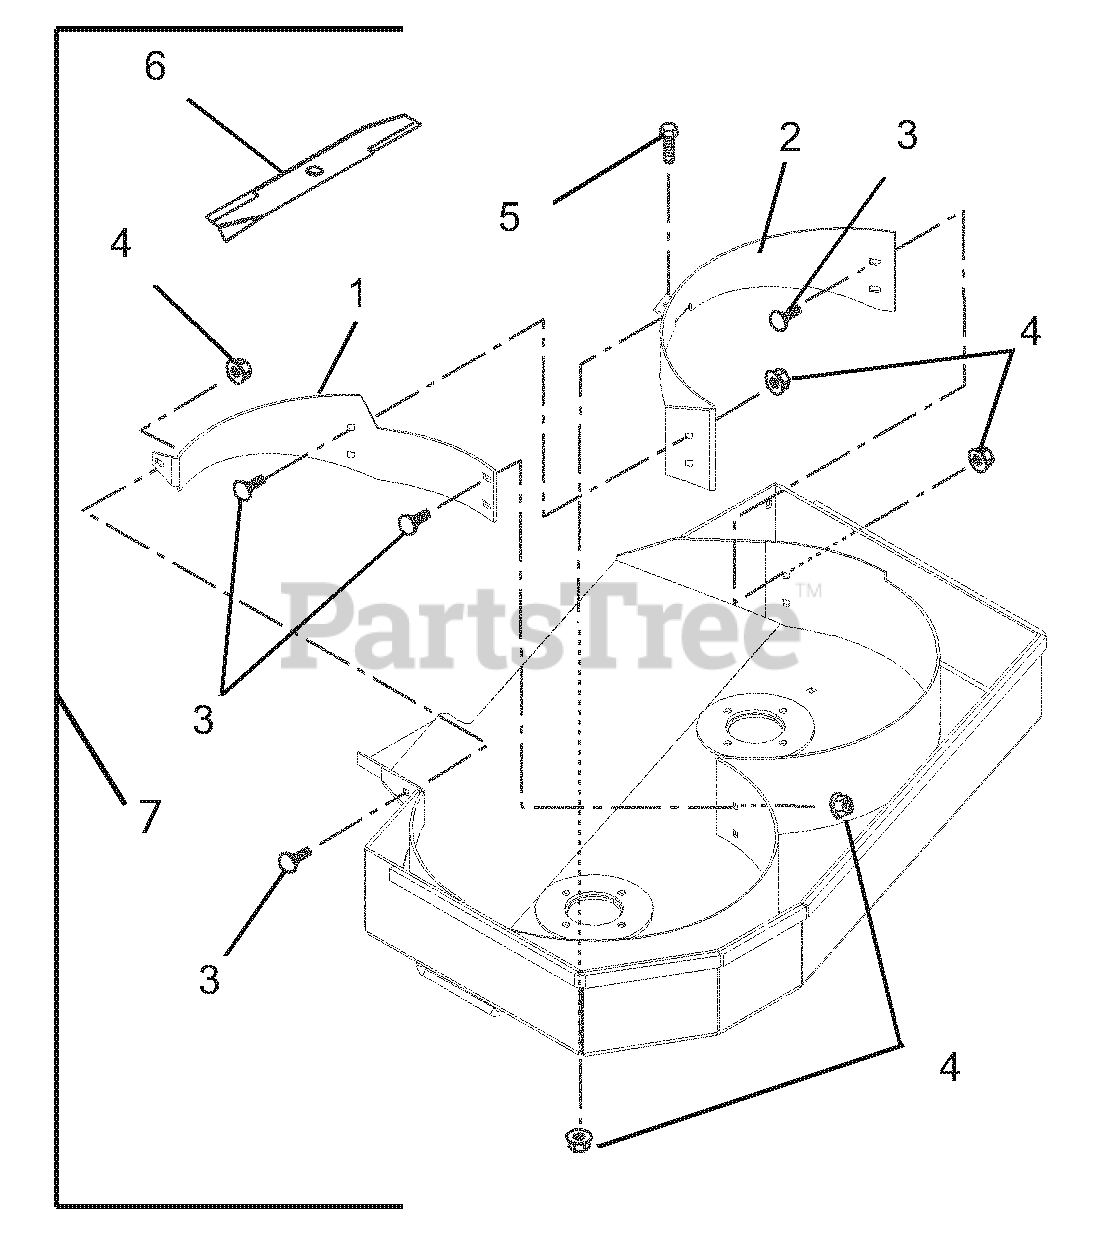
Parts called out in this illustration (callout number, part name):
1	BAFFLE-MULCH-LEFT REAR-36" RD
1	BAFFLE-MULCH-LEFT REAR-32" RD
2	BAFFLE-MULCH-RIGHT REAR-36" RD
3	@BLT-RDHDSQNK .31-18X.75 G5YZ
4	@NUT-LK-TOP-FLG .31-18 YWZC
5	@BLT-HEX .31-18X.75 GR5 YWZC
6	BLADE, MULCH 18.00"
6	BLADE, MULCH 16.25
7	KIT-MULCHING-36" REAR DISCHARG
7	KIT-MULCHING 32" REAR DISCHARG
